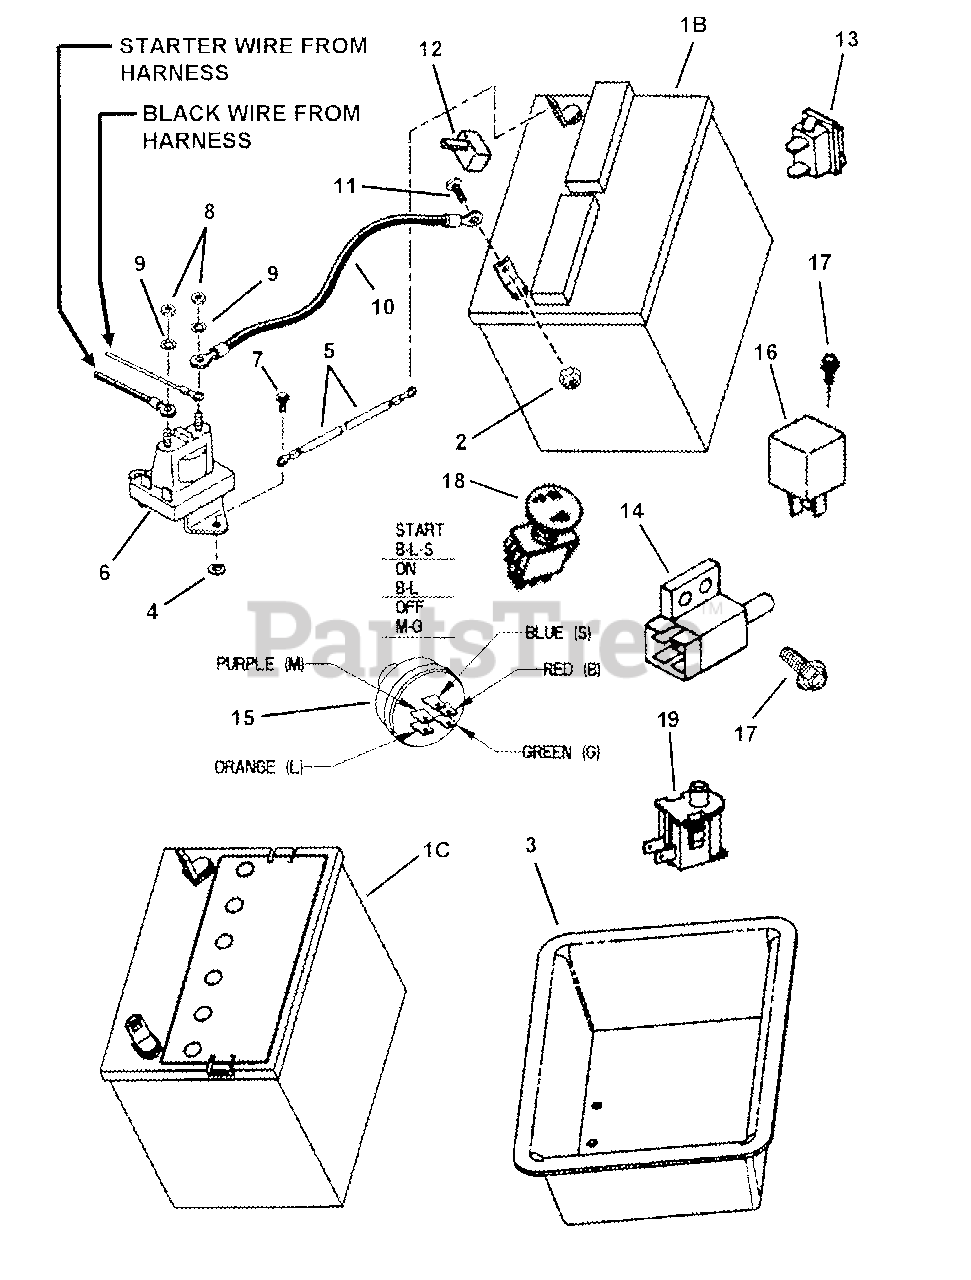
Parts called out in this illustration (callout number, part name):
1B	BATTERY, 12v 195 cca, 7 plates/cell, wet
1C	BATTERY, 12v 300 cca, 9 plates/cell, wet
2	NUT, 1/4-20 Hex Nyloc
3	TRAY, Battery
4	RETAINER, 1/4" Bolt
5	WIRE, Ground, Black
6	SOLENOID- Super Trombetta- 2 Terminal
7	SCREW, 1/4-20 x 1/2" Hex Washer Self-Tap
8	NUT, 1/4-20 Hex Jam
9	WASHER, 1/4" Internal Tooth Lock
10	WIRE, Positive (Red) (solenoid to battery)
11	SCREW, 1/4-20 x 5/8" Hex Head Cap, GR 5
12	COVER, Battery Cable
13	LIGHT SWITCH, Rocker, SPST
14	SWITCH- DPDT
15	SWITCH, Ignition-Afterfire Solenoid
16	RELAY, Operator Presence Control, Electric Clutch
17	SCREW, #10-24 x 1/2" Hex Washer Self-Tap (Torx)
18	SWITCH, PTO Electric Clutch
19	SWITCH, Seat (NC)
